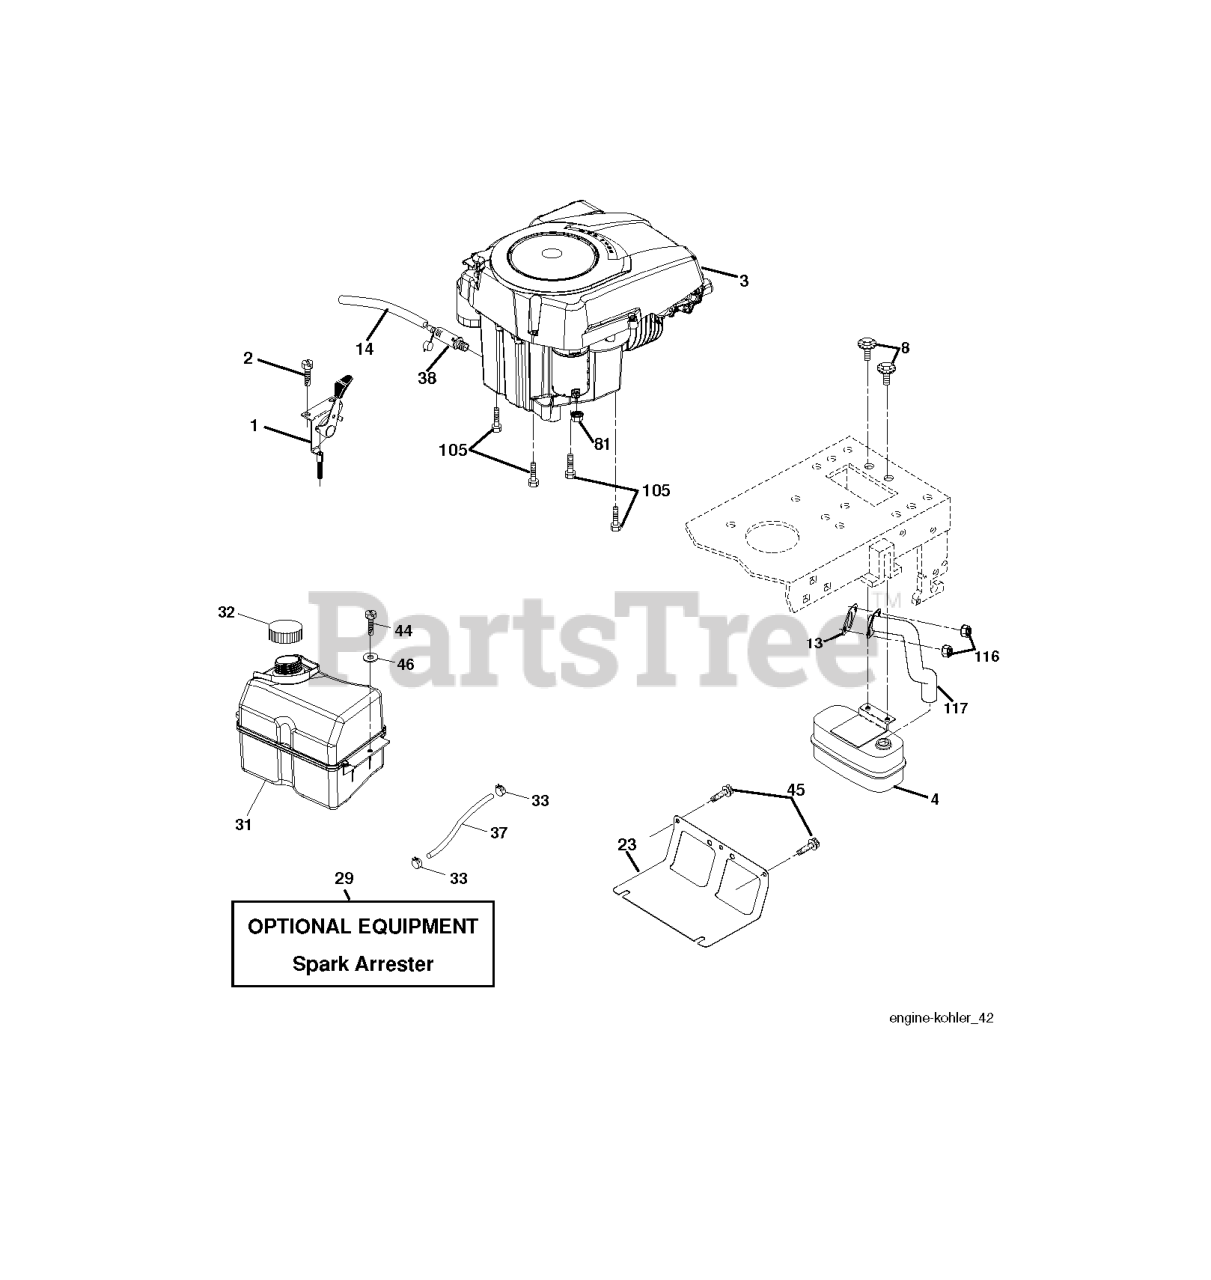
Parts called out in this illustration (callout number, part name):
1	CONTROL.TH/CK.C.
2	SCREW
4	MUFFLER.SINGLE.CYL.KOHL/B&S
8	BOLT.5/16-18UNCX3/4 W/SEMS.BLK
13	GASKET.EXHAUST.KOHLER
14	TUBE, DRAIN OIL ASM.
23	SHIELD.BROWNING.DBR.GUARD
29	KIT.SPARK ARRESTOR 794945 B&S
31	RP TANK FUEL FRT 1.5 GAL
32	FUEL CAP
33	HOSE CLAMP
37	LINE.FUEL.20
38	PLUG DRAIN OIL EASY
44	SCREW HEXWSHR 1/4-20X3/4
45	SCREW, 3/8-16X3/4
46	WASHER
81	NUT
105	SCREW 3/8-16X1
116	NUT.HEX.FLANGE.TOPLOCK
117	RP.TUBE.EXHAUST.KOHL.COURAGE
